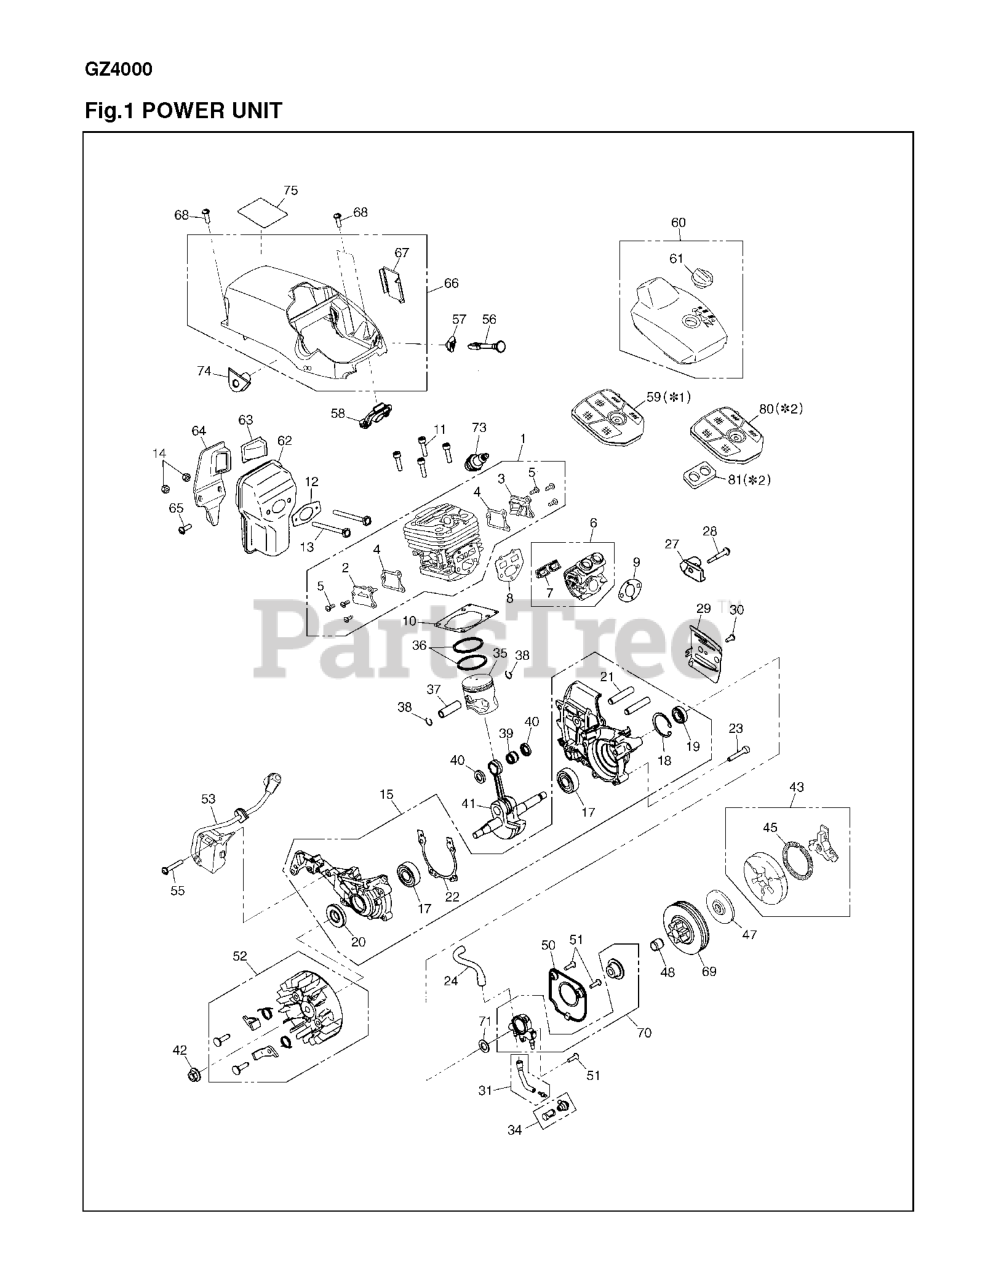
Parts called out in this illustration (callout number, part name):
1	CYLINDER ASSY
2	TR COVER MAG
3	TR COVER PTO
5	SCREW
6	INSULATOR
12	GASKET, MUFFLER
15	CRANKCASE ASSY
17	BEARING
21	STUD BOLT
24	PIPE
27	CATCHER (RPLS 848C3066F1)
29	PLATE(A)
30	SCREW
31	PIPE IN COMP.(RPLS 848C306731)
34	FILTER COMP (RPLS T210023200)
35	RP PISTON
36	RING.PISTON
39	ROLLER BEARING
40	WASHER
41	SHAFT COMP
42	NUT
43	CLUTCH ASSY(RPLS T210051200)
48	ROLLER BEARING
51	SCREW
52	ROTOR COMP
53	COIL ASSY
55	SCREW
56	ROD.CHOKE
59	CLEANER ASSY
60	COVER COMP
63	ARRESTER, SPARK
65	RP_SCREW
66	COVER COMP
69	DRUM.3/8-6
70	OIL PUMP SET(RPLS T210055110)
73	PLUG CMR7H
